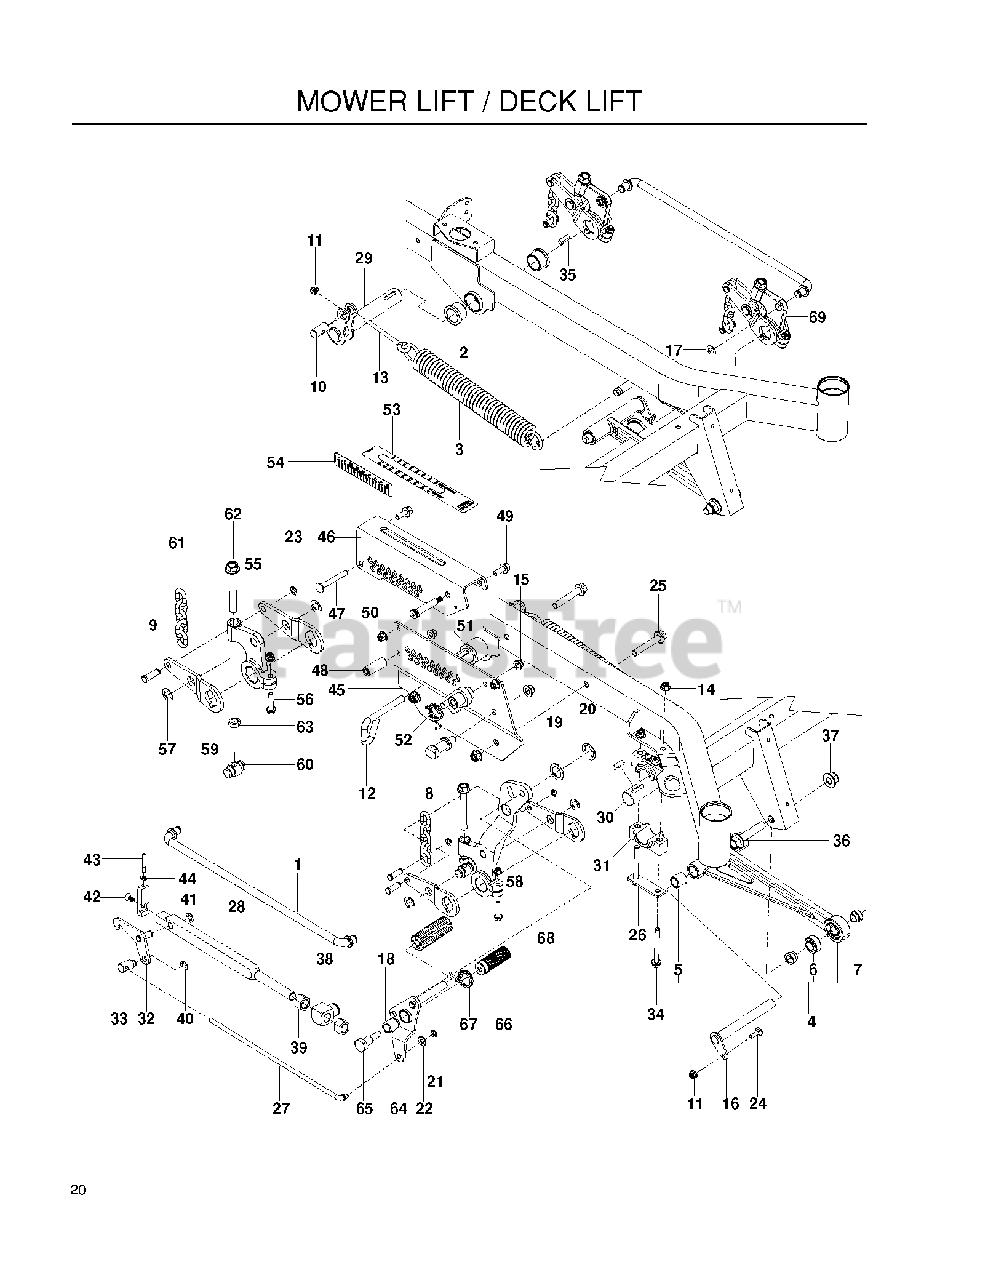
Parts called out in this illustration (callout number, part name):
1	ROD, LIFT
2	BUSHING, FLANGE 1.25 X 1.0
3	SPRING, EXTENSION
4	ASSEMBLY, STRUT
5	BUSHING, SLEEVE 3/4 X 1.0
6	BALL JOINT, 3/4" SWIVEL
8	GUIDE, HEIGHT BAR
9	PIN, 7/16 CLEVIS
10	PIVOT, SPRING
11	5/16-18 NYLOC FLANGE NUT
12	PIN, HEIGHT
13	EYE BOLT 4.5`
14	NUT 3/8-16 HEX FLG NYLOC ZD
15	NUT, 1/2-13 HEX FLG NYLOC ZD
16	PIN, STRUT
17	E-RING 5/8
18	BUSHING, SLEEVE 3/4 X 1.0
19	MACHINE BUSHING
20	E-RING 1"
21	E RING 3/8"
22	WASHER 3/8 SAE FLAT
23	RING, E, 7/16
24	RHSNB 5/16C X 1
25	HFFS 1/2-13 X 3 GD 5 ZD
26	PLATE, PILLOW BLACK
27	ROD, HEIGHT LATCH
28	BAR, HEIGHT
29	SHAFT, RR LIFT
30	SHAFT, LIFT, FT
31	BLOCK, PILLOW
32	LATCH, HEIGHT WLDMT
33	SWIVEL, HEIGHT LATCH
34	HHFS 3/8-16 X 3.5 GD 5 ZD
35	KEY, 5/16 SQ X 1.0
36	HHFS 5/8-11 X 3.0 GD 8 ZD
37	NUT 5/8-11 FLG NYLOC ZD
38	SWIVEL, HEIGHT BAR
39	Hex Nut, 3/4-10
40	E-RING 1/2 (2 2)
41	CAP, HEIGHT BAR
42	SCREW, 5/16-18 X 3/4 FLAT HEX
43	LINK, INDICATOR
44	NUT 1/4-20 JAM
45	PLATE, INNER HEIGHT, BLUE
46	PLATE, OUTER HEIGHT, BLUE
47	3/8-16 X 3` CARR BOLT
48	SPACER, HEIGHT PLATE
49	HHFS 3/8-16 X 1 GRD 5 ZD
50	BOLT, SHOULDER, 1/2 X 2.25
51	LATCH, TRANSPORT WLDMT
52	SPRING, TORSION
53	DECAL, HEIGHT
54	DECAL, HEIGHT
55	ARM, CAST LIFT
56	HHFS 5/16-18 X 1.5 GD 5
57	E RING 3/4
58	ARM, LIFT LEVER
59	ARM LIFT BLK
60	SHAFT, LIFT TRUNION
61	LIFT CHAIN
62	HHFS 1/2-13 X 4 GR 5
63	NUT 1/2 HEX JAM
64	PEDAL, RELEASE WLDMT
65	BOLT, SHOULDER
66	PAD, FOOT PEDAL
67	SPRING, TORSION
68	PEDAL, DECK HEIGHT
69	ASSEMBLY, DECK LIFT CRANK
